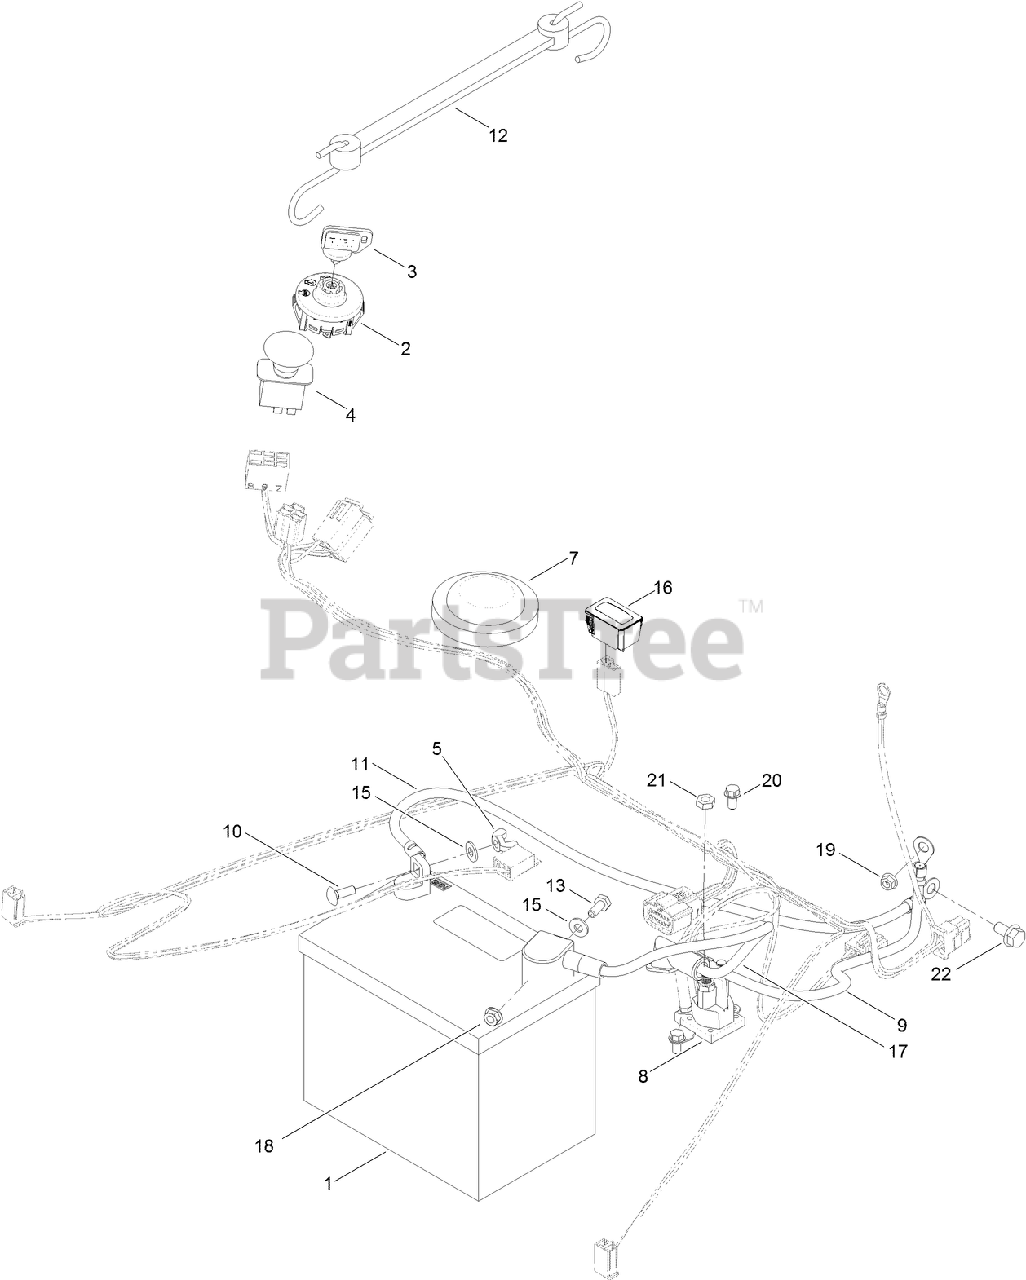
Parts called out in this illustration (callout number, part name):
1	BATTERY
3	KEY-IGNITION
4	SWITCH-PTO
5	NUT-WING
7	SWITCH-SEAT
8	SOLENOID
9	CABLE-BATTERY, POSITIVE
10	BOLT-CARR
11	CABLE-BATTERY, BLACK
12	HOLDDOWN-BATTERY
13	SCREW-HH
15	WASHER-FLAT
16	HOURMETER
17	CABLE-BATTERY, RED
18	NUT-HF
19	NUT-HF
20	SCREW-HWH
21	NUT-JAM
22	SCREW-HHF
